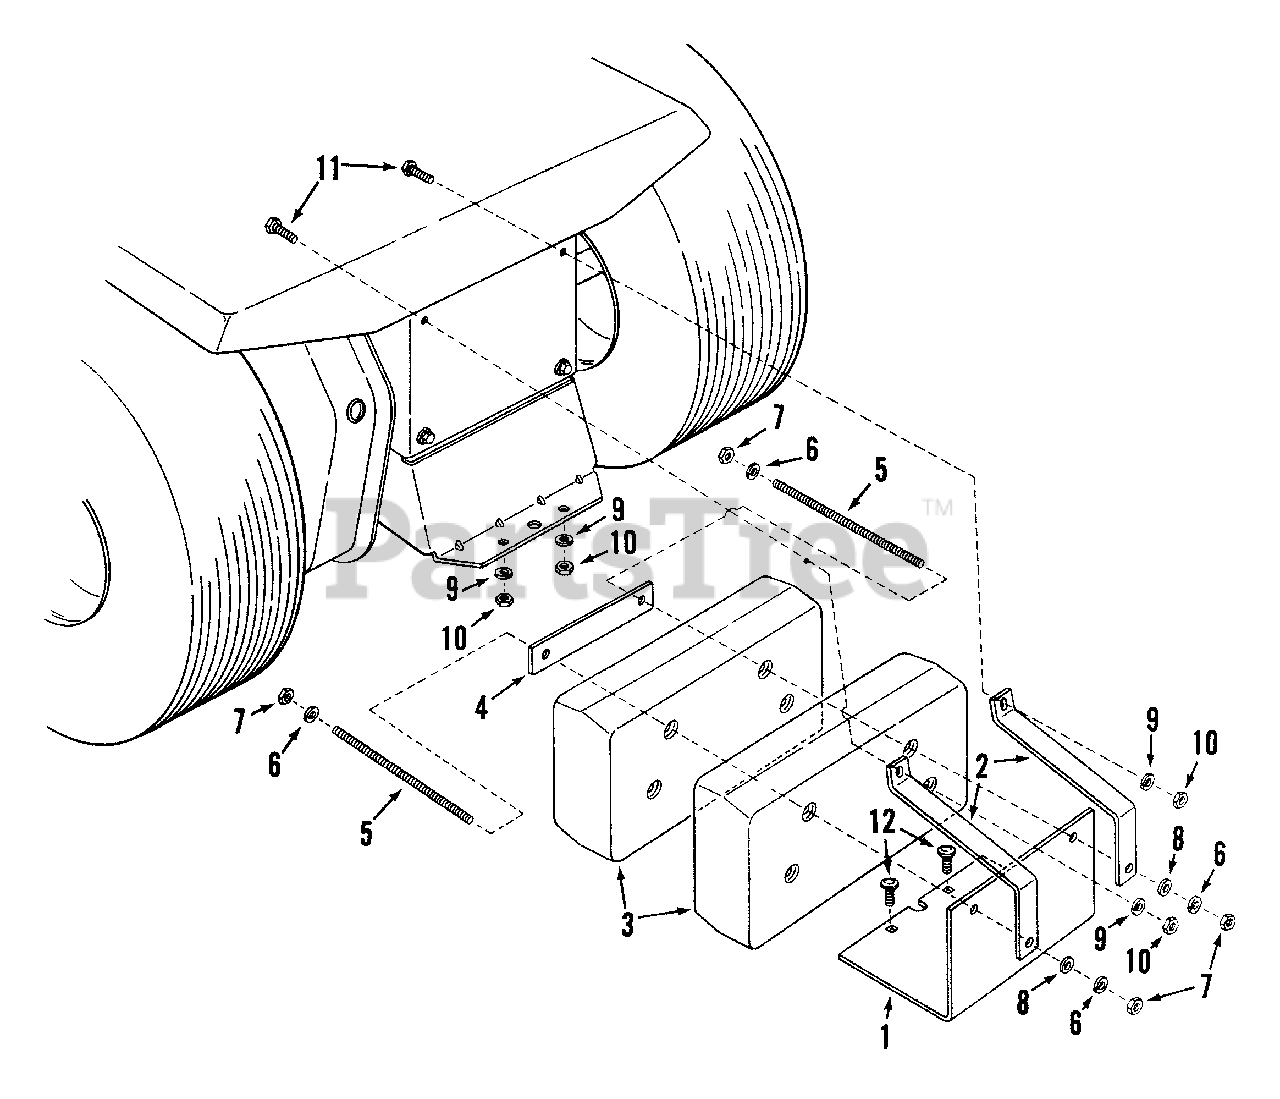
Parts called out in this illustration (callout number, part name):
2	SUPPORT
3	WEIGHT (38 lb.)
4	PLATE, Retainer
5	ROD, 3/8-16x9"Threaded
6	WASHER, 3/8 Split Lock
7	NUT, 3/8-16 Hex
8	WASHER, 3/8 Flat SAE
9	WASHER, 5/16 Split Lock
10	NUT, 5/16-18 Hex
11	SCREW, 5/16-18x1"Hex Head Cap
12	BOLT, 5/16-18x1"Carriage
